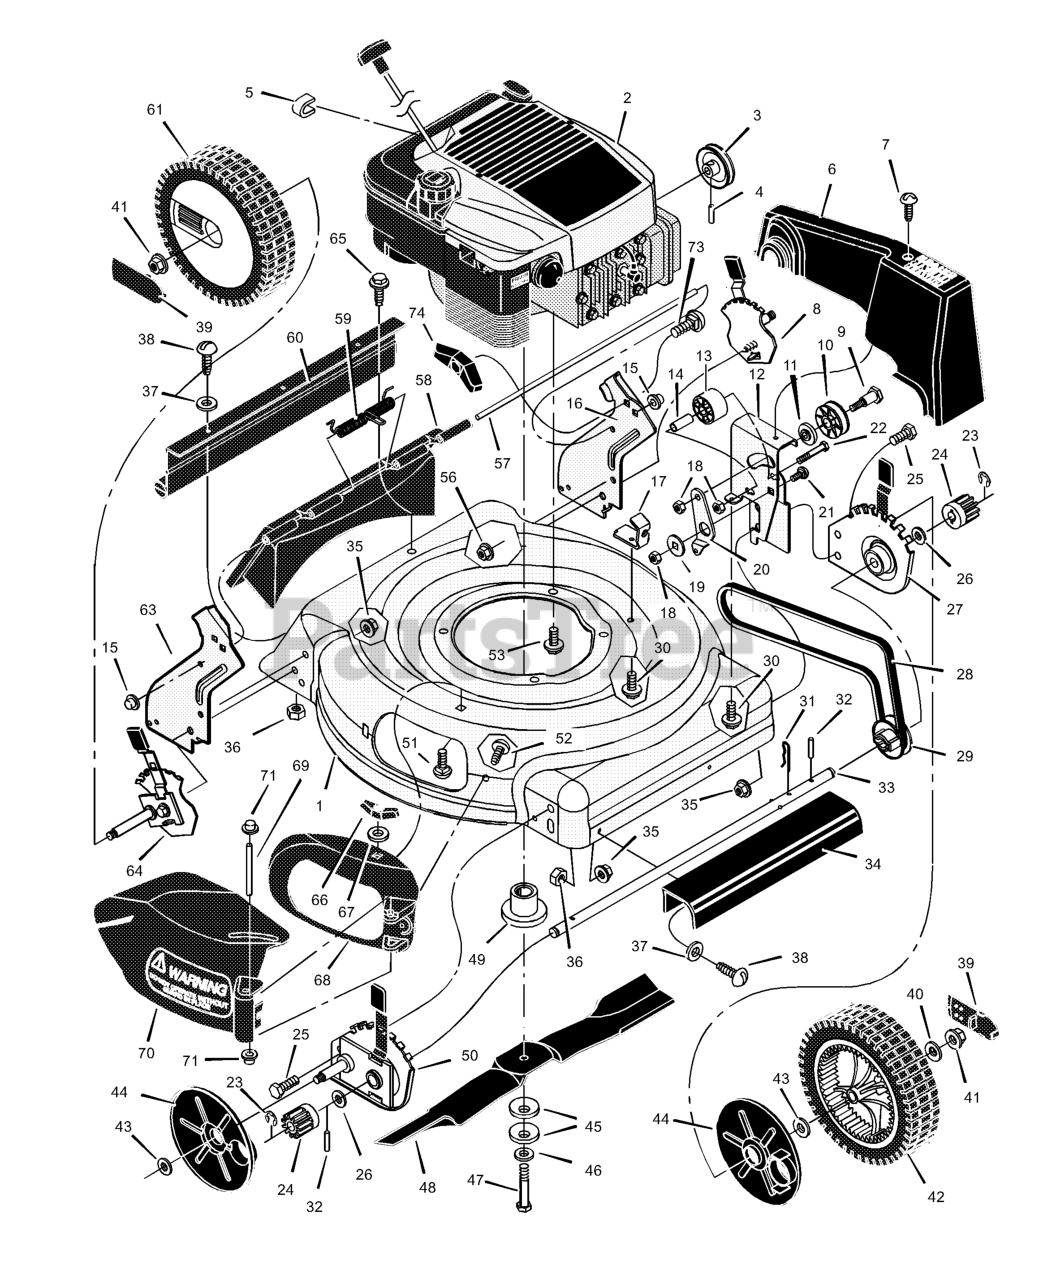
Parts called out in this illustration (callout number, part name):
1	Housing
2	Engine
3	Pulley, Engine
4	Pin, Spring
6	Cover, Belt (Black)
8	Adjuster, Left Rear Height
9	Bolt, Shoulder
12	Bracket, Idler Support
13	Pulley, Idler -Rear
14	Bearing
15	Nut, Push
16	Bracket, Left Handle
17	Bracket, Cable
18	Nut, Hex
20	Arm, Idler
21	Bolt, Carriage
22	Bolt, Shoulder
24	Gear, Pinion
25	Bolt
27	Adjuster, L. Frt. Height
29	Pulley, Axle
31	Pin, Hair
32	Pin, Spring
34	Cover, Axle (Black)
35	Nut, Flange
36	Nut, Hex
39	Cap, Hub
40	Washer
41	Nut, Flange
42	Wheel, Drive
44	Cover, Dust
45	Washer, Belleville
49	Adapter, Blade
50	Adjuster, R. Frt. Height
51	Bolt, Carriage
53	Bolt, Engine
55	Washer
56	Nut, Flange
57	Rod, Pivot
58	Door, Rear (Black)
59	Spring
60	Deflector, Rear
61	Wheel, Rear
63	Bracket, Right Handle
64	Adjuster, R. Rear Hgt.
66	Wingnut
67	Retainer, Push
68	Bezel (Black)
69	Pin, Pivot
70	Deflector, Chute (Black)
71	Push On Cap
73	Bolt, Carriage
